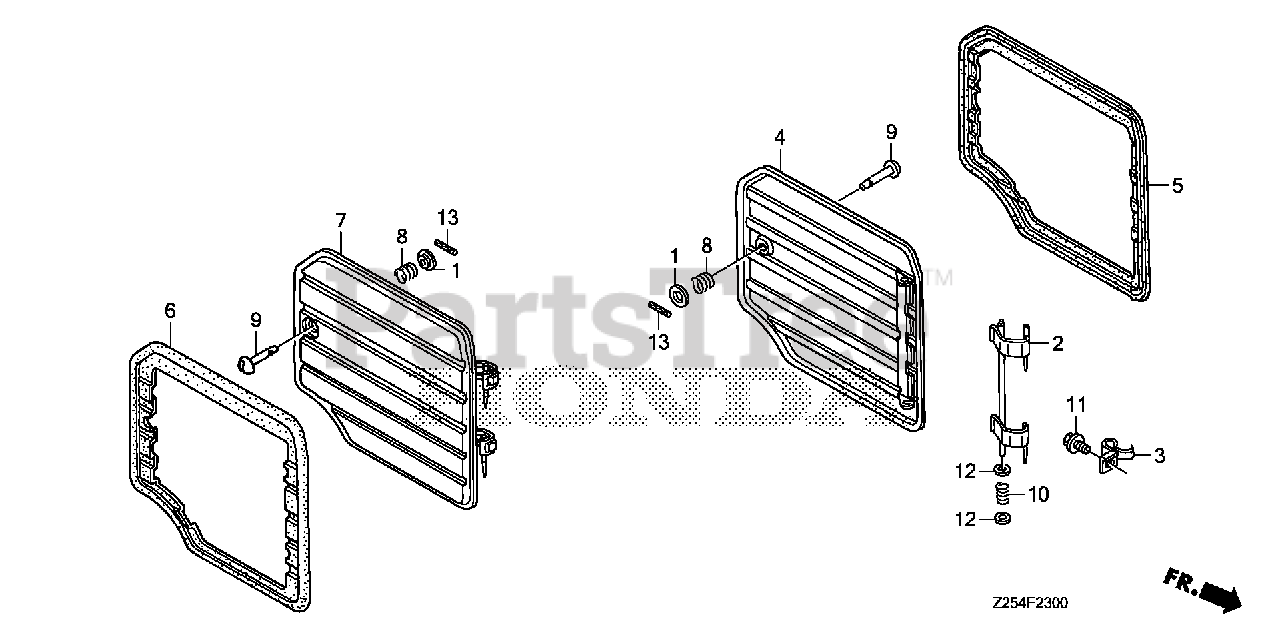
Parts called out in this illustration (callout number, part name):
1	RETAINER, LOCK SPRING
2	HINGE, R. MAINTENANCE COVER
3	SPRING, HINGE PLATE
4	COVER, R. MAINTENANCE *R280* (POWER RED)
5	SEAL, R. MAINTENANCE COVER
6	SEAL, L. MAINTENANCE COVER
7	COVER, L. MAINTENANCE *R280* (POWER RED)
8	SPRING, COVER LOCK
9	PIN, COVER LOCK
10	SPRING, MAINTENANCE COVER
11	BOLT, FLANGE (5X8)
12	WASHER (8MM)
13	PIN, SPRING (4X20)
